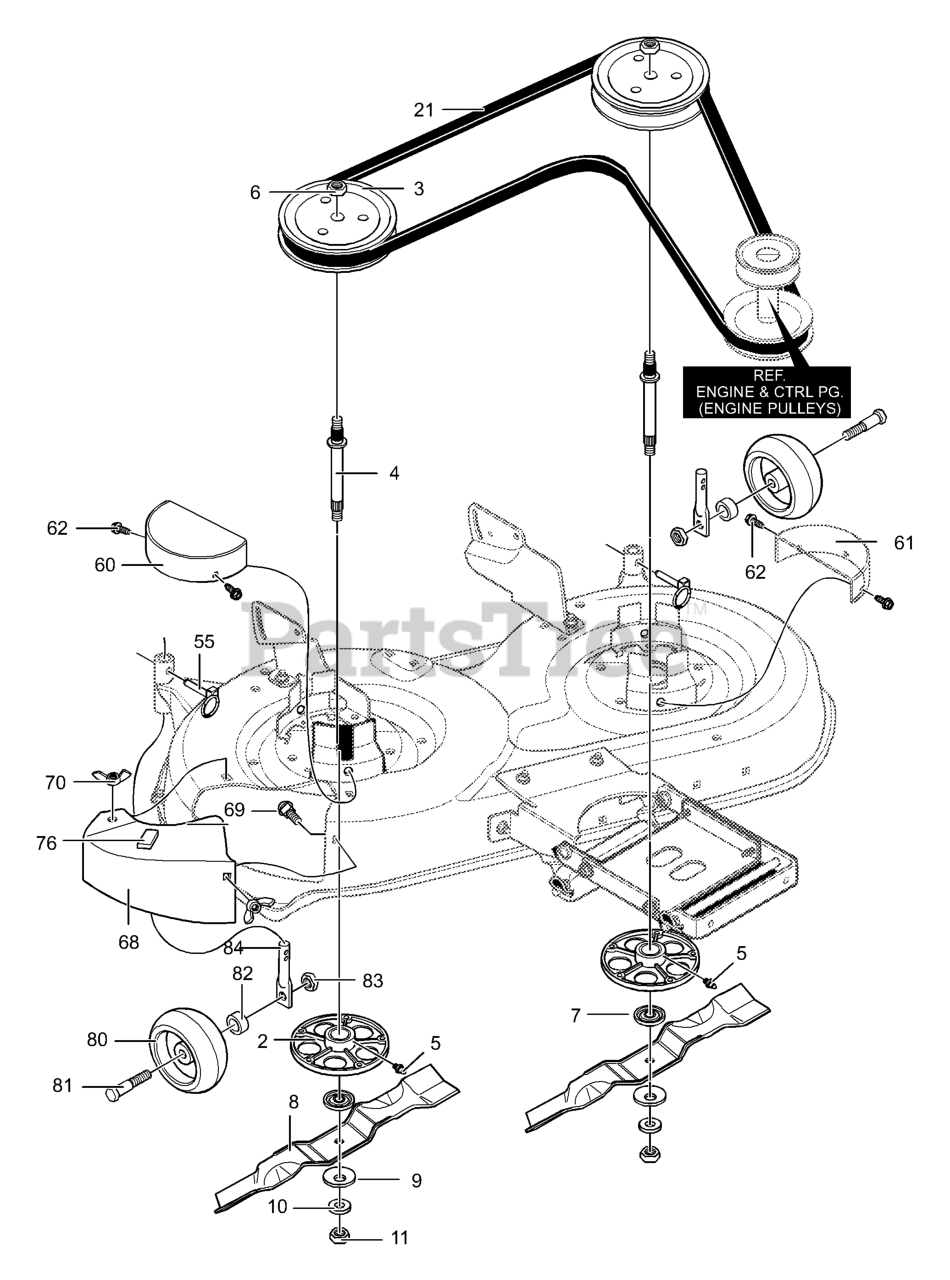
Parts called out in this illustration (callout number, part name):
2	HOUSING, JACKSHAFT
3	PULLEY, SPLIT STEEL 42"
4	JACKSHAFT
5	ZERK, GREASE
6	NUT, 9/16-18
7	ADAPTER, BLADE
8	42" (3-N-1) BLADE
21	BELT, 42" DECK
55	PIN, LYNCH
60	GUARD, Belt R.H.
61	GUARD, Pulley L.H.
62	SCREW
68	COVER, DISCHARGE MULCH
69	BOLT
70	NUT, WING
76	PAD, ADHESIVE
80	WHEEL, GAUGE
82	SPACER, SLV NYLON
83	NUT
84	ROD, GAGE SHORT
